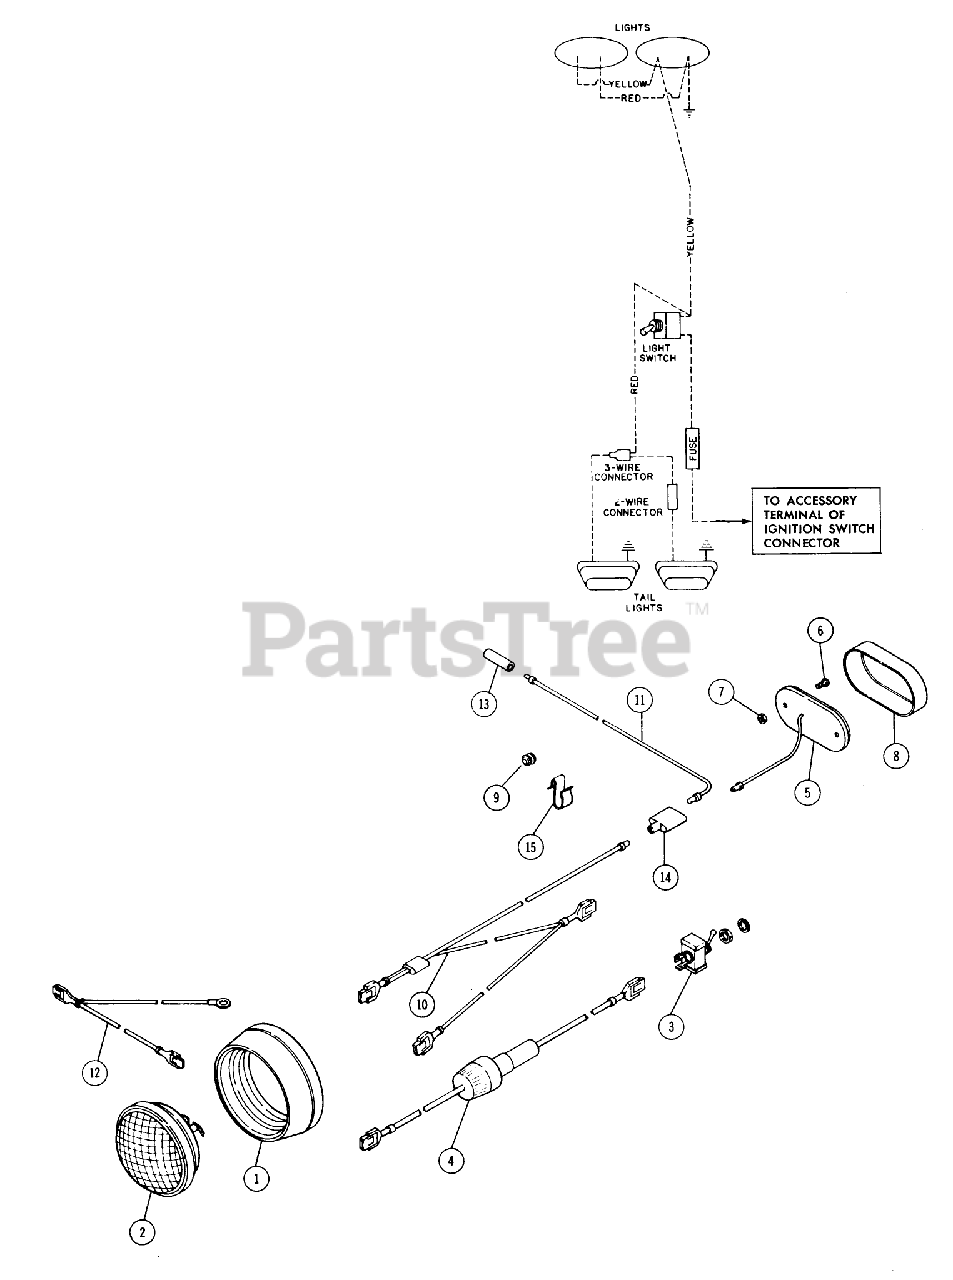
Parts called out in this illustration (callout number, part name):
1	Grommet
2	HEADLAMP
3	SWITCH-LIGHTS
4	ASSY FUSED CONNECTOR
5	Base-Taillight
6	Screw, 10-32 X 5/8
7	HEX NUT 10-32 E.S.
8	Lens-Taillight
9	Grommet
10	Control Clip
11	Wire assembly
12	Wire Assy
13	CONNECTOR 2 WIRE
14	CONNECTOR 3 WIRE
15	SPEED CLIP
